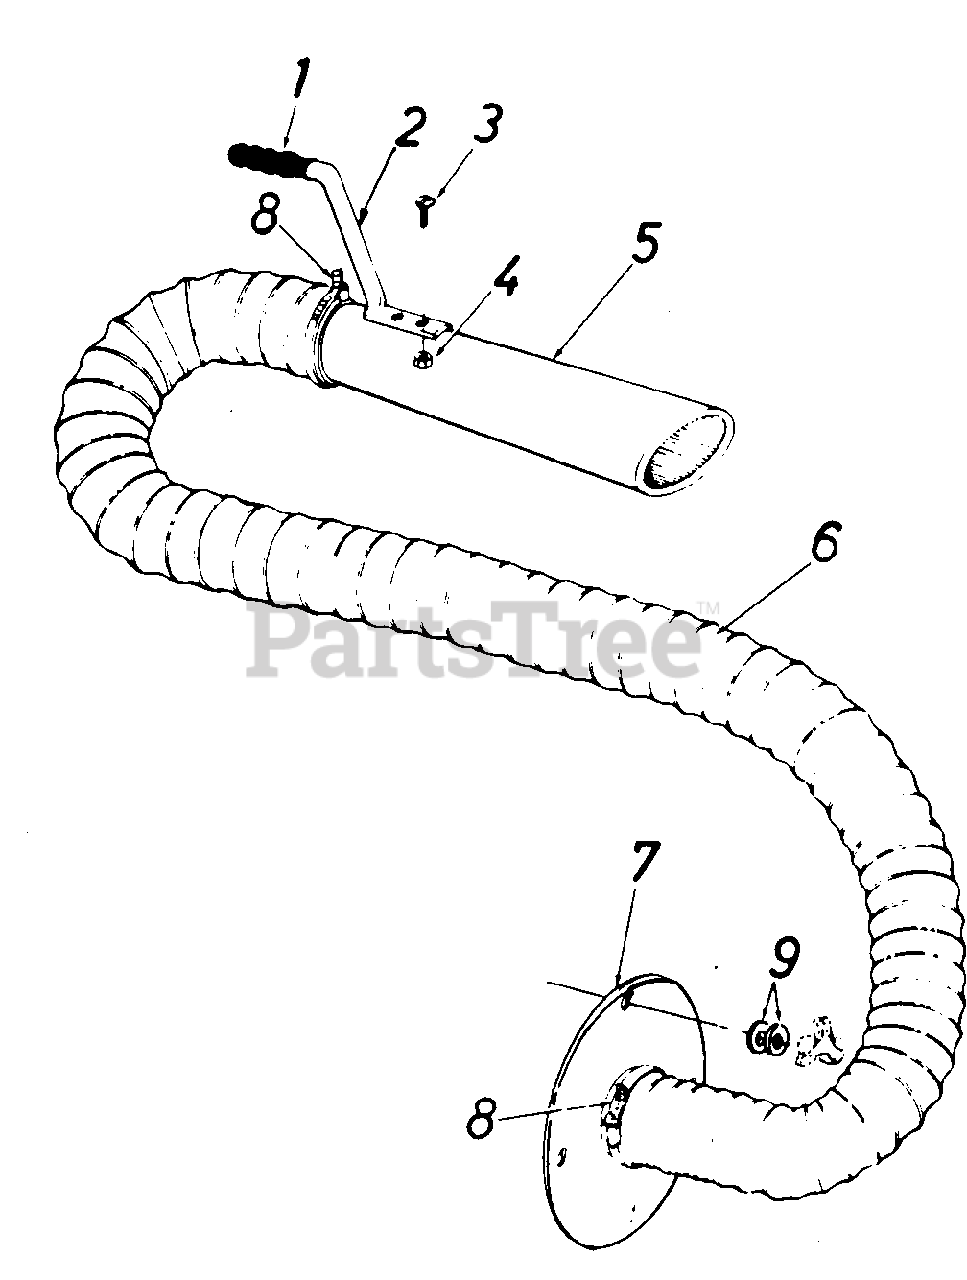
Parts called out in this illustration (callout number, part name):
1	GRIP-BLACK
2	HANDLE-HOSE NOZ LONG
3	SCREW-TRUSS SEMS #10-24 X .50
5	NOZZLE-HOSE
6	HOSE-4IN DIA X 10FT
9	WASHER-FL-.312 X 1.125 X .125
